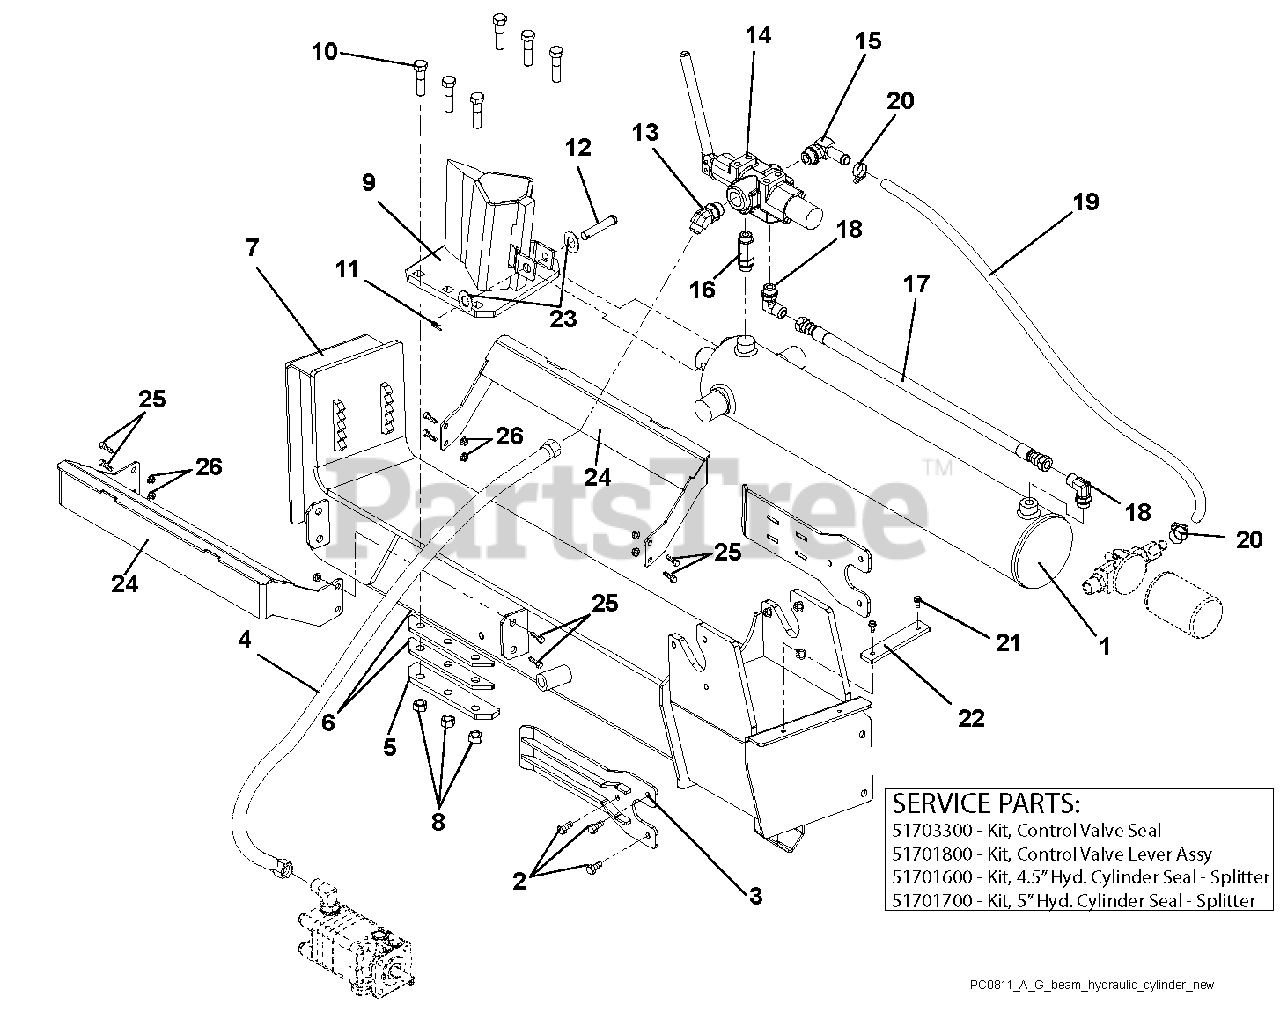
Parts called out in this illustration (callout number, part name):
1	Cylinder, 4.5-Inch With Decals (917003)
1	Kit, 4.5" Hydraulic Cylinder Seal - Splitter
1	Cylinder, 5-In. With Decals (917004)
1	Kit, 5" Hydraulic Cylinder Seal - Splitter
2	Bolt, Hex .31-18 x 1.00
3	Plate, Stripper
4	Hose Assembly, 8M3K-8FJX-8FJX-46
5	Retainer, Wedge
6	Spacer, Wedge
7	Beam, Splitter
8	Nut, Locking Center Flange .50-13
9	Weldment, Splitter Wedge
10	Bolt, Round Head Square Neck .50-13 x 2.00 Grade 8
11	Clip, Spring
12	Pin, Clevis .494 x 2.50, Bright Zinc Plating
13	Fitting, Hydraulic 6802-8-10
14	Valve, Splitter Control
14	Kit, Control Valve Seal
14	Kit, Control Valve Lever Assy
15	Fitting, Hydraulic 4601-10-10
16	Fitting, Hydraulic 6403-NWO-8-8-L
17	Hose Assembly, 8M3K-8FJX-8FJX-22
18	Fitting, Hydraulic 6801-8-8
19	Hose, Hydraulic Return 10LOLA x 53-In.
20	Clamp, .88 Diameter
21	Screw, Tapping Hex Washer Head Thread Rolling .25-20 x .50 (917003)
22	Spacer, Cylinder (917003)
23	Washer, Flat Steel .563 x 1.38 x .109
24	Cradle, Log
25	Bolt, Hex .38-16 x 1.00 Grade 5
26	Nut, Top Flange Locking .38-16
